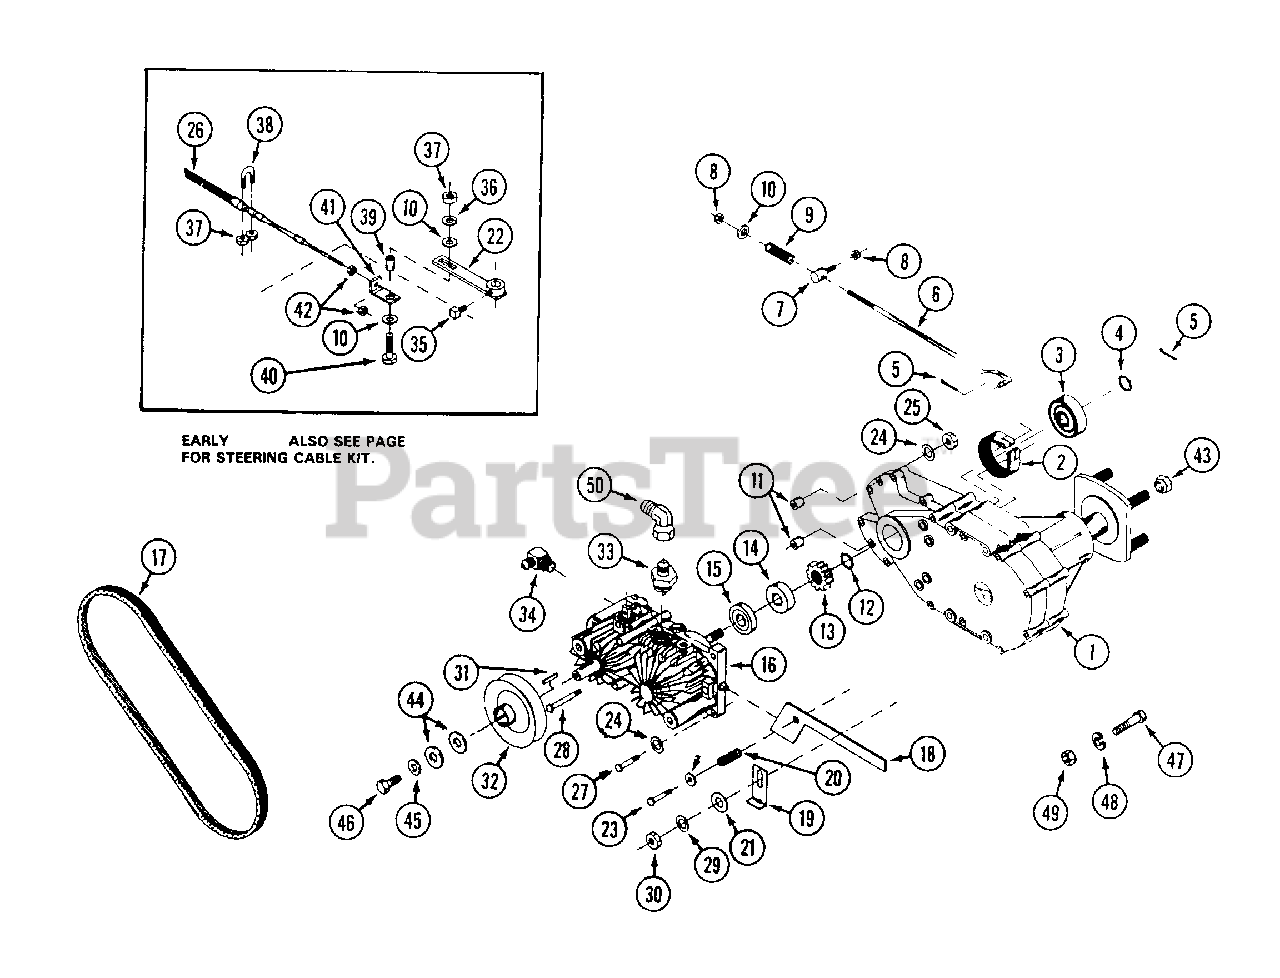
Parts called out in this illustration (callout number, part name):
1	TRANSMISSION - ZT
5	PIN - cotter 1/8" x 1"
8	NUT - lock 1/4" - 20
12	RING - snap
14	BEARING
16	PUMP - hydro L.H.
17	BELT - pump drive
18	LEVER - transmission dump
19	BRACKET - dump lever stop
20	SPRING - compression
21	WASHER - 3/8"
22	ARM - transmission
23	BOLT - dump lever
24	LOCKWASHER - 5/16"
25	NUT - 5/16" - 18
26	CABLE - steering 58"
27	BOLT - 5/16" - 18 x 1-3/4"
28	BOLT - 5/16" - 18 x 7-1/2"
29	LOCKWASHER - 3/8"
30	NUT - 3/8" - 16
31	KEY - 5 x 5 x 25 mm
32	PULLEY - 4" O.D. x 15 mm ID
33	FITTING - male adapter
34	FITTING - male adaptor 90°
35	SCREW - set 5/16" - 18 x 1/2" square head
36	LOCKWASHER - 1 /4"
37	NUT - 1/4" - 20
38	CLAMP - cable
39	BUSHING - cable
40	BOLT - 1/4" - 20 x 1"
41	BRACKET - cable end
42	NUT lock #10 - 32
43	NUT - lug 1/2" - 20
44	WASHER - .625" x 1"
45	WASHER - .312" x,875"
46	BOLT - M6 - 1.0 x 12 mm flange
47	BOLT - 3/8" - 16 x 3-1/2" mounting
48	LOCKWASHER - 3/8"
49	NUT - 3/8" - 16
50	FITTING - 90° male to female
